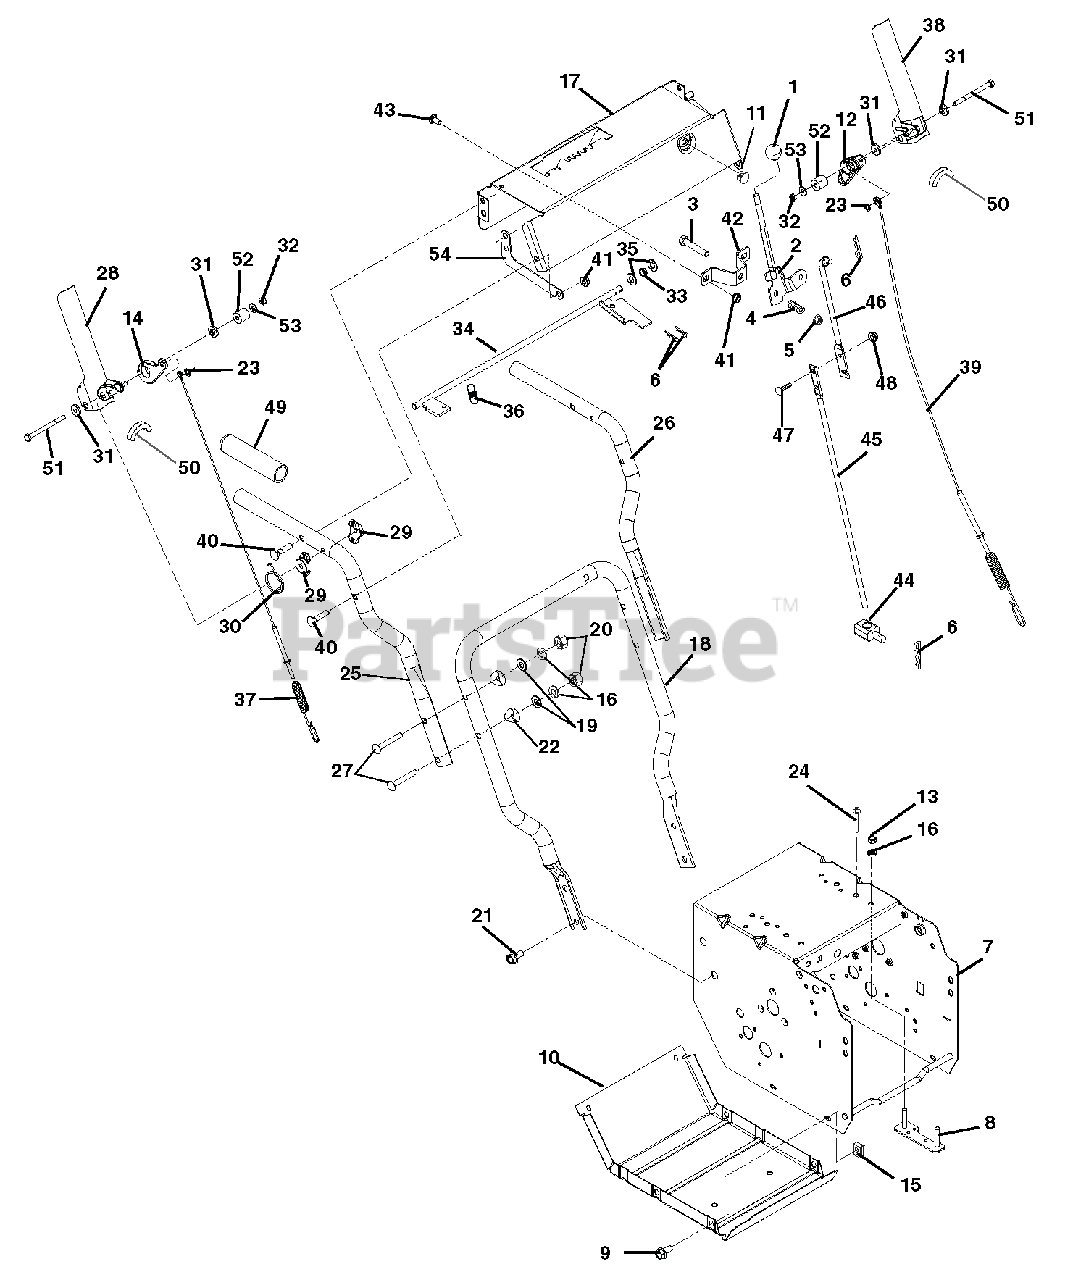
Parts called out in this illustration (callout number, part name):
1	KNOB,BALL -BLACK 1.47" .375-16
2	WMT, SHIFT LEVER
3	@BLT-HEX .38-16X2.00 GR5 YWZC
4	SG-COMP .125X.781X1.250
5	@NUT-LK-TOP-FLG .38-16 YWZC
6	PIN-HAIR INT .08X.18X1.18 YWZC
7	FRAME, 920/921
8	STRAP, ENGINE BOLT-WELDMENT
9	BLT-HEX .25-20X.75 HWH YZ GR5
10	COVER, BOTTOM
11	HOLE PLUG, PLASTIC .44 HOLE
12	CAM, INTERLOCK - LH
13	@NUT-HEX .31-18 YWZC
14	CAM, INTERLOCK - RH
15	NUT-RTNR .25-20X.56
16	WSHR-LK .312X.097 HVY YWZC
17	DASH, SNO TEK (W/DECALS)
18	HANDLEBAR, LOWER (COMPACT)
19	@WSHR-FL-STL.38X.875X.083 YWZC
20	@NUT-LK-NYL .312-18 YWZC
21	BLT-SERHFWH .38-16X.75 YWZC
22	SPACER, HANDLEBAR
23	RG-RTNG-EXT .250X.010
24	RVT-POP .187 YZ
25	HANDLEBAR, UPPER - RH COMP/DEL
26	HANDLEBAR, UPPER - LH COMP/DEL
27	@BLT-RDHDSQNK .31-18X2.25 G5YZ
28	PADDLE, CLUTCH - RH COMPACT
29	SPACER, HANDLEBAR
30	SPRING, TORSION
31	BSHG, FLG .266X.42X.150 PM
32	NUT-JAM-NYL .250-20 W/INSERTYZ
33	BUSHING, POLYLINER-.38 SNAPIN
34	WELDMENT, INTERLOCK SHAFT
35	@WSHR-FL-STL.406X.812X.065 YWZ
36	SPRING, EXTENSION
37	CABLE, ATTACHMENT, COMPACT
38	PADDLE, CLUTCH - LH COMPACT
39	CABLE, TRACTION - COMPACT
40	BLT-RDHDXLSQNK .31-18X1.5 G5YZ
41	@NUT-LK-TOP-FLG .31-18 YWZC
42	BRKT, SHIFT MOUNT
43	@BLT-RHDSSQNK .31-18X.62 G5YZ
44	PIVOT,SHIFT ROD .375-16(TRUNN)
45	ROD, SHIFT - LOWER
46	ROD, SHIFT - UPPER
47	@BLT-RDHDSQNK .25-20X.75 G5YZ
48	@NUT-LK-TOP-FLG .25-20 YWZC
49	HANDLE GRIP
50	EDGING, CLUTCH PADDLE - 2.00"
51	@BLT-HEX .25-20X3.25 YWZC
52	BSHG, SLV .266 X .750 X .750
53	@WSHR-FL-STL.281X.62X.065 YWZC
54	STRAP, SUPPORT - DASH PANEL
